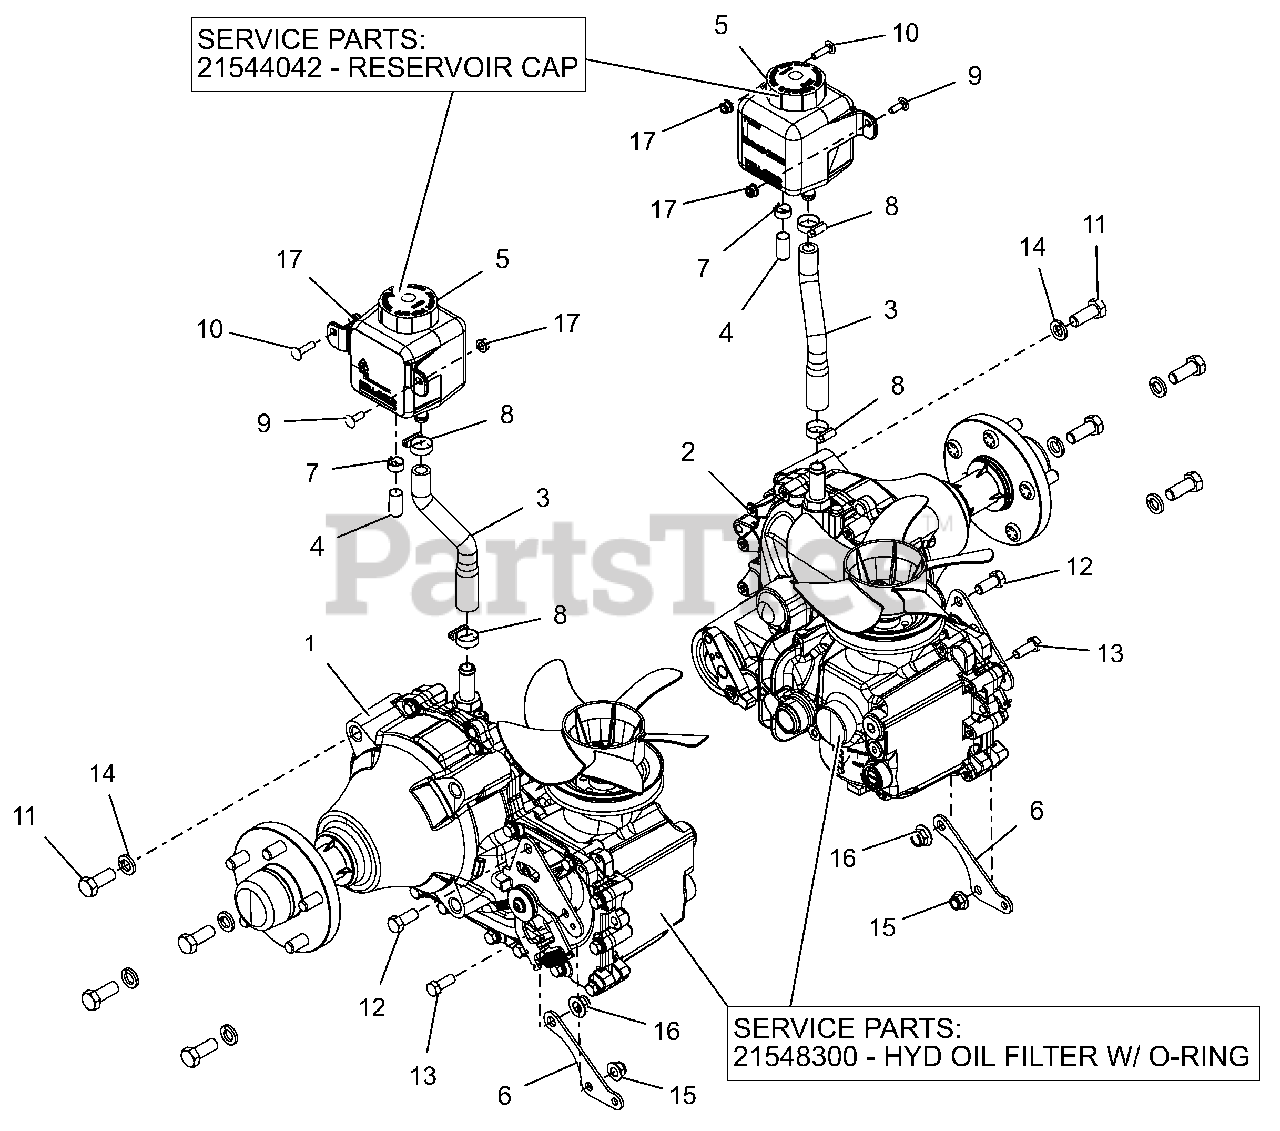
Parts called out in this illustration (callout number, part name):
1	TRANS, RH HG ZT-5400
1	FILTER,HYD OIL W/ORING ZT-54OO
2	TRANS, LH HG ZT-5400
2	FILTER,HYD OIL W/ORING ZT-54OO
3	HOSE,PT200/400 TRANS OVERFLOW
4	CAP, .50 BARBED FITTING
5	TANK, HYDRO OVERFLOW 700 ML
5	CAP, HYDRO RESERVOIR REPLAC.
6	DRV CNTRL LINKAGE MTG BRKT-BLK
7	CLAMP, .62 SPRING
8	CLAMP,.88 DIA. HOSE
9	@BLT-RDHDSQNK .25-20X.75 G5YZ
10	@BLT-RDHDSQNK .25-20X1.00 G5YZ
11	@BLT-HEX .50-13X1.25 GR5 YWZC
12	@BLT-HEX .44-14X1.00 GR5 YWZC
13	@BLT-HEX .38-16X1.00 GR5 YWZC
14	@WSHR-LK .50X.125 REG YWZC
15	@NUT-LK-NYL-FLG .38-16 YWZC
16	@NUT-LK-NYL-FLG .44-14 YWZC
17	@NUT-LK-NYL-FLG .25-20 YWZC
